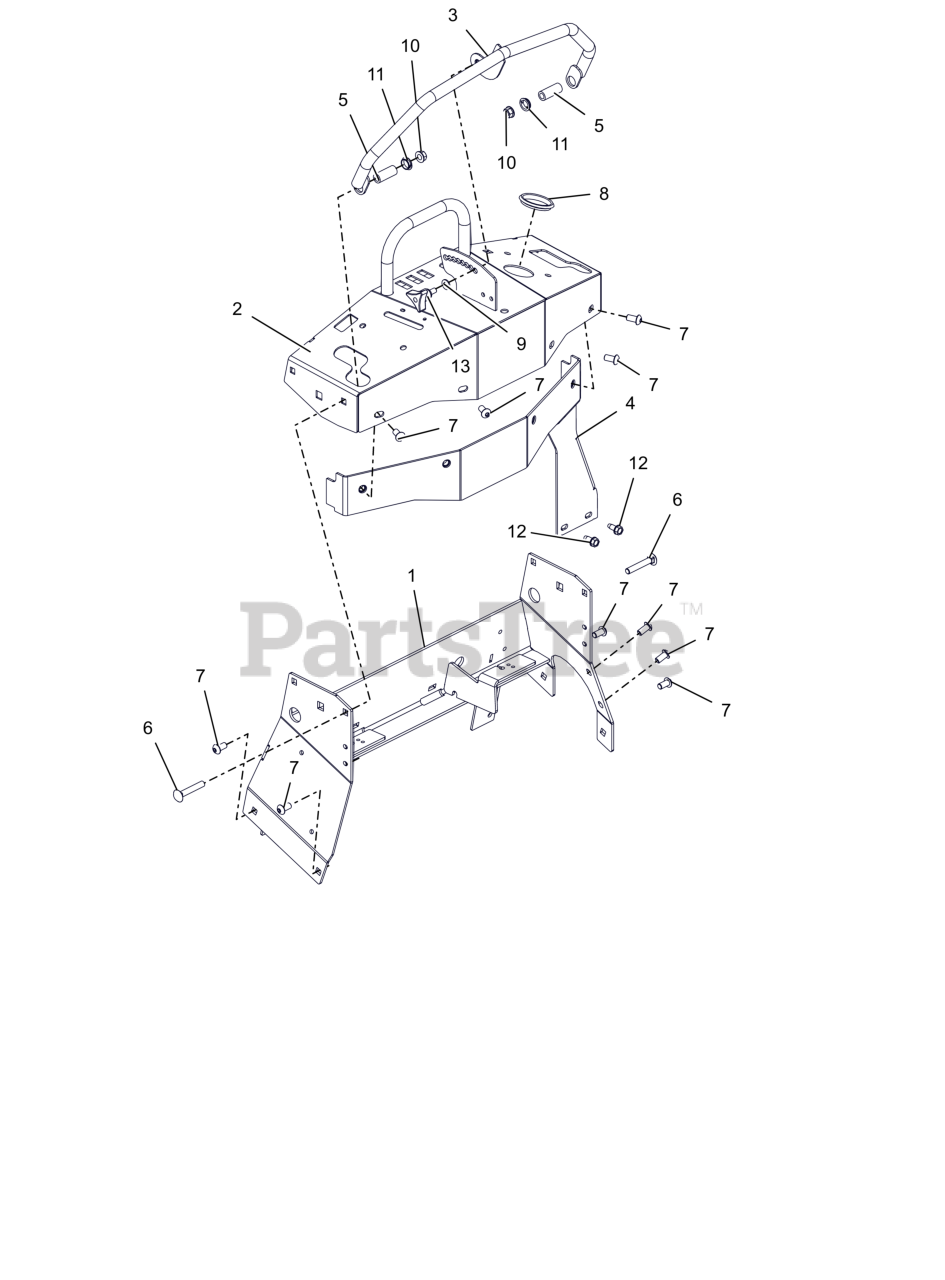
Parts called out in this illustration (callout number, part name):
1	WLDMT, TOWER (RED)
2	WLDMT, DASH (RED)
3	WLDMT, CRUISE BAR
4	WLDMT, DASH ACCENT (BLACK)
5	SPACER, .375 X .625 X 1.54
6	BLT,RHSN .38-16X2.25 G5 ZCC
7	SCR,BTNHD .375-16X.75 ZCC
8	GROMMET, RUBBER 1.89 ID
9	WSHR,FLT .344X.688X.065 ZCC
10	NUT-LK-CTR-FLG .375-16 GF ZCC
11	BUSHING, POLYLINER-.63 SNAPIN
12	SCR,TAP .312-18X.75 HWH TR ZCC
13	KNOB,WING STUD 5/16-18 X .75
